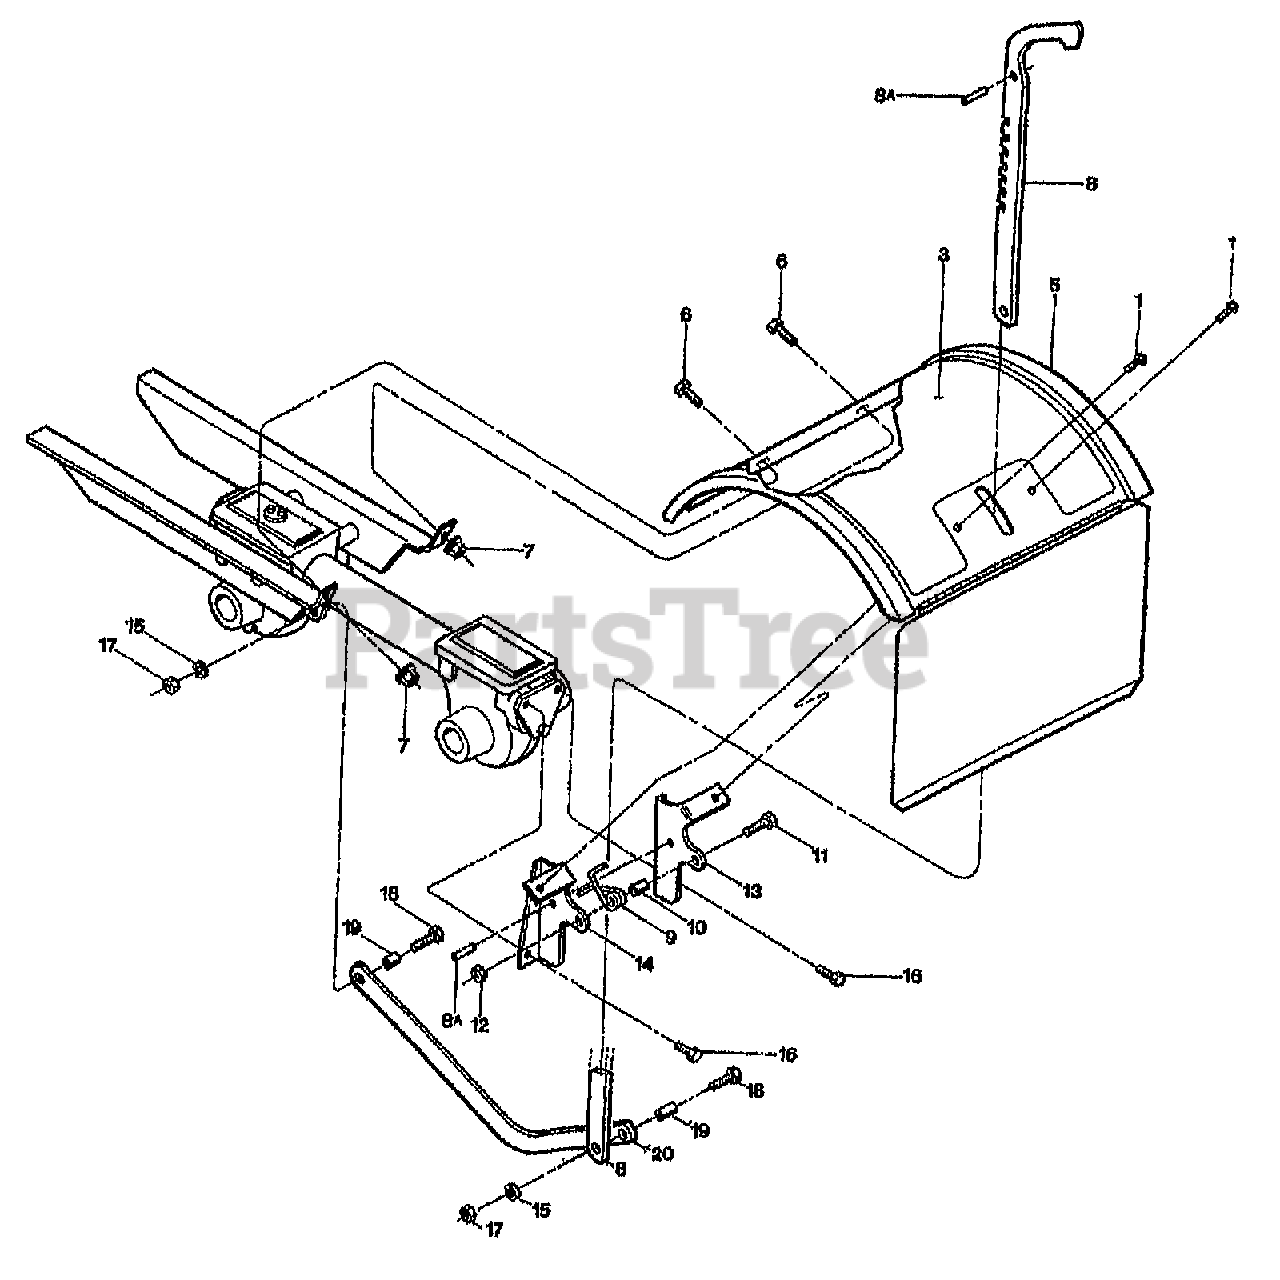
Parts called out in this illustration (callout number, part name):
1	SCR-HWH 1/4-20 X .5 STH
2	REF. NO. 2 IS NOT USED
3	DECAL-HOOD OPER INST
3	DECAL-HOOD INST TUFFY {12155}
4	REF. NO. 4 IS NOT USED
5	HOOD W/DECALS PNT (INCL. TINE FLAP & 55101)
5	HOOD W/DECALS TUFFY (INCL. TINE FLAP & 55101)
6	SCR-HH 5/16-18X.5 GD5 YEL
7	NUT-HFLK 5/16-18 ZP
8	DEPTH REG-W/PIN PNT
8A	PIN-ROLL .25 X 1
9	SPRING-TORSION
10	SPACER-.250X.343X.375
11	SCR-HH 1/4-20X1.0
12	NUT-LK 1/4-20
13	BRKT-HOOD RIGHT PNT
14	BRKT-HOOD LEFT PNT
15	WASHER-LK .312 ZP
16	SCR-HFLK 5/16-18X1.00 ZP
17	NUT-HEX 5/16-18 ZP
18	SCR-HH 5/16-18X1.25 G5ZP
19	BUSHING-.438X.323X.4
20	DRAG BAR-TUFFY PNT
